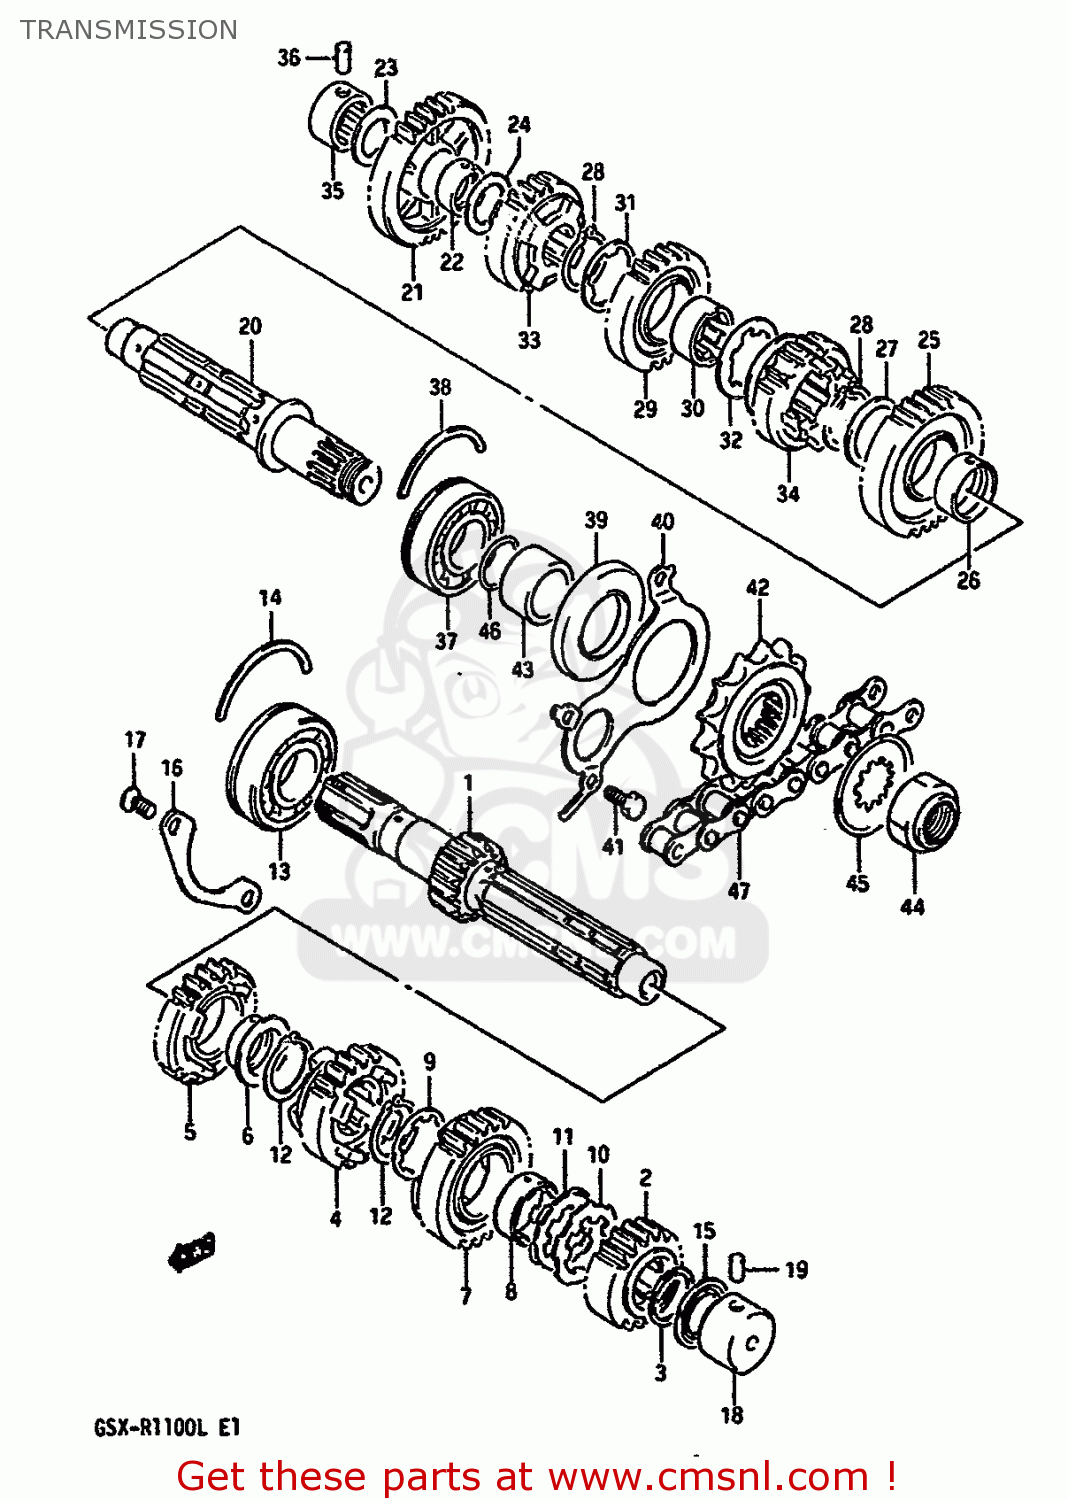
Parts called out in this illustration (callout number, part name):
1	SHAFT,COUNTER
2	GEAR,2ND DRIVE(NT:19)
3	CIRCLIP
4	GEAR,THIRD DRIVE (NT:20)
5	GEAR,FOURTH DRIVE (NT:22)
6	BUSHING
7	GEAR,FIFTH DRIVE (NT:23)
8	BUSH,5TH DRIVE GEAR
9	WASHER,LOCK
10	WASHER,LOCK
11	WASHER
12	RING,SNAP
13	BEARING(25X62X17)
14	C-RING
15	SEAL,OIL(20X31.2X2.7)
16	RETAINER,CNTR SHAFT BEARING
17	SCREW
18	BEARING(20X34X17.5)
19	PIN
20	SHAFT,DRIVE
21	GEAR,FIRST DRIVEN
22	BUSHING
23	WASHER
24	WASHER
25	GEAR,SECOND DRIVEN
26	BUSH(28X32X11)
27	WASHER
28	CIRCLIP
29	GEAR,THIRD DRIVEN
30	BUSHING,THIRD DRIVEN GEAR
31	WASHER,LOCK
32	WASHER,LOCK
33	GEAR,FOURTH DRIVEN (NT:23)
34	GEAR,FIFTH DRIVEN
35	BEARING(20X34X20)
36	PIN
37	BEARING(25X62X19)
38	C-RING
39	SEAL,OIL(34X62X6)
40	RETAINER,DRIVE SHAFT OIL SEAL
41	BOLT
42	SPROCKET,ENGINE(15T)
43	SPACER(25X34X22.7)
44	NUT
45	WASHER,LOCK
46	O RING(D:1,ID:24.5)
47	CHAIN,DRIVE(118LE)
